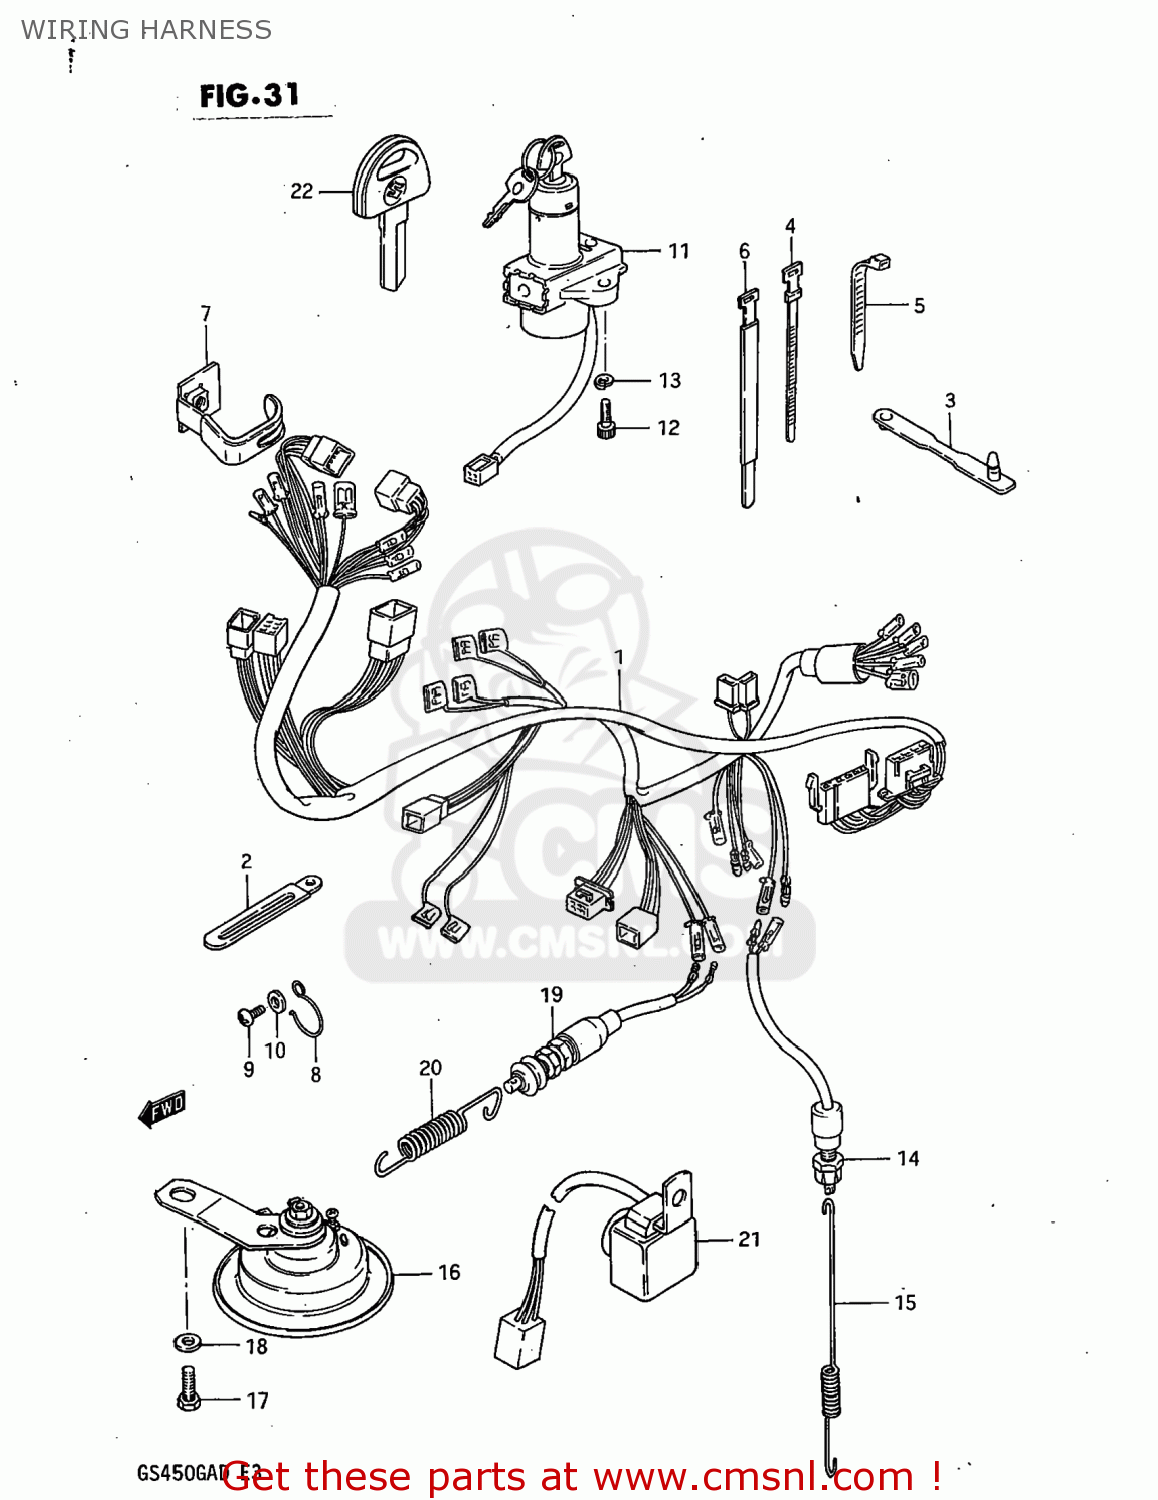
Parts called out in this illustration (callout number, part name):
1	HARNESS,WIRING
2	CLAMP
3	CLAMP,L:88
4	CLAMP(L:80)
5	CLAMP(L:125)
6	CLAMP
7	CLAMP,WIRING HARNESS
8	CLIP,WIRING HARNESS
9	SCREW 6X12
10	WASHER
11	LOCK ASSEMBLY,STEERING
12	BOLT
13	LOCK WASHER
14	SWITCH ASSEMBLY,STOP LAMP
15	SPRING
16	HORN ASSEMBLY
17	BOLT 8X12
18	WASHER
19	SWITCH ASSEMBLY,SIDE STAND
20	SPRING
21	BUZZER ASSEMBLY,TURN SIGNAL
22	KEY,BLANK
